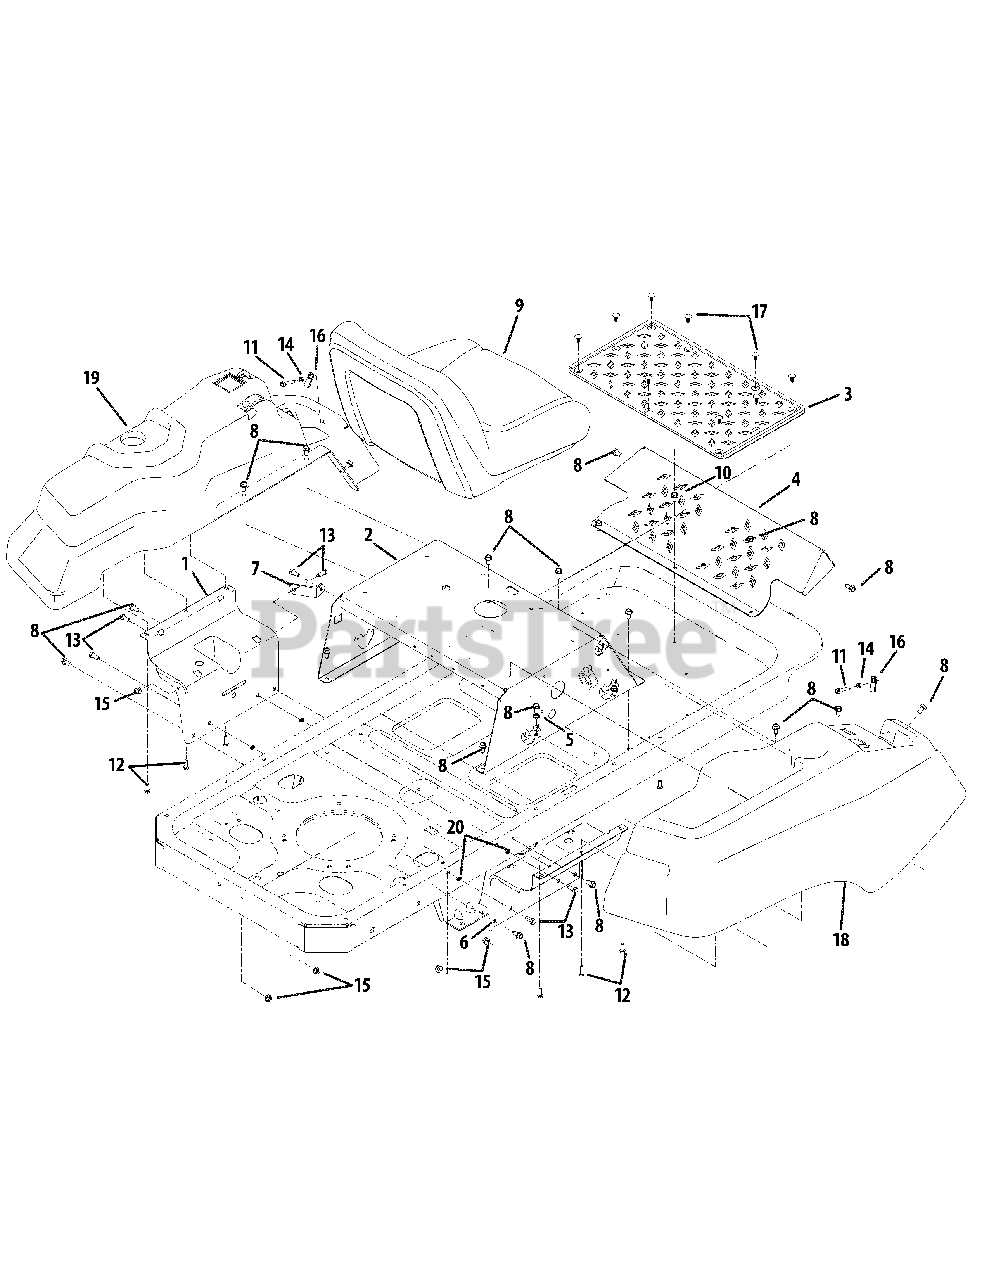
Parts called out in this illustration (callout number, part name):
1	Console Mount Bracket
3	Foot Pad
5	Lock Washer, 3/8
6	Console Mount Bracket
7	Fuel Tank Support Bracket
8	Hex Washer Screw, 5/16-18 x .750
9	High-Back Seat
10	Hex Washer Screw, 5/16-18 x .825
11	Hex Washer Screw, 1/4-20 x 1.500
12	Hex Washer Screw, 1/4-15 x .750
13	Hex Screw, 5/16-18 x .75
14	Jam Nut, 1/4-20
15	Flange Lock Nut, 5/16-18
16	U-Type Nut, 1/4-20
17	Ratchet Clip, .250
18	RH Console
19	LH Console
20	Speed Nut, .3125
